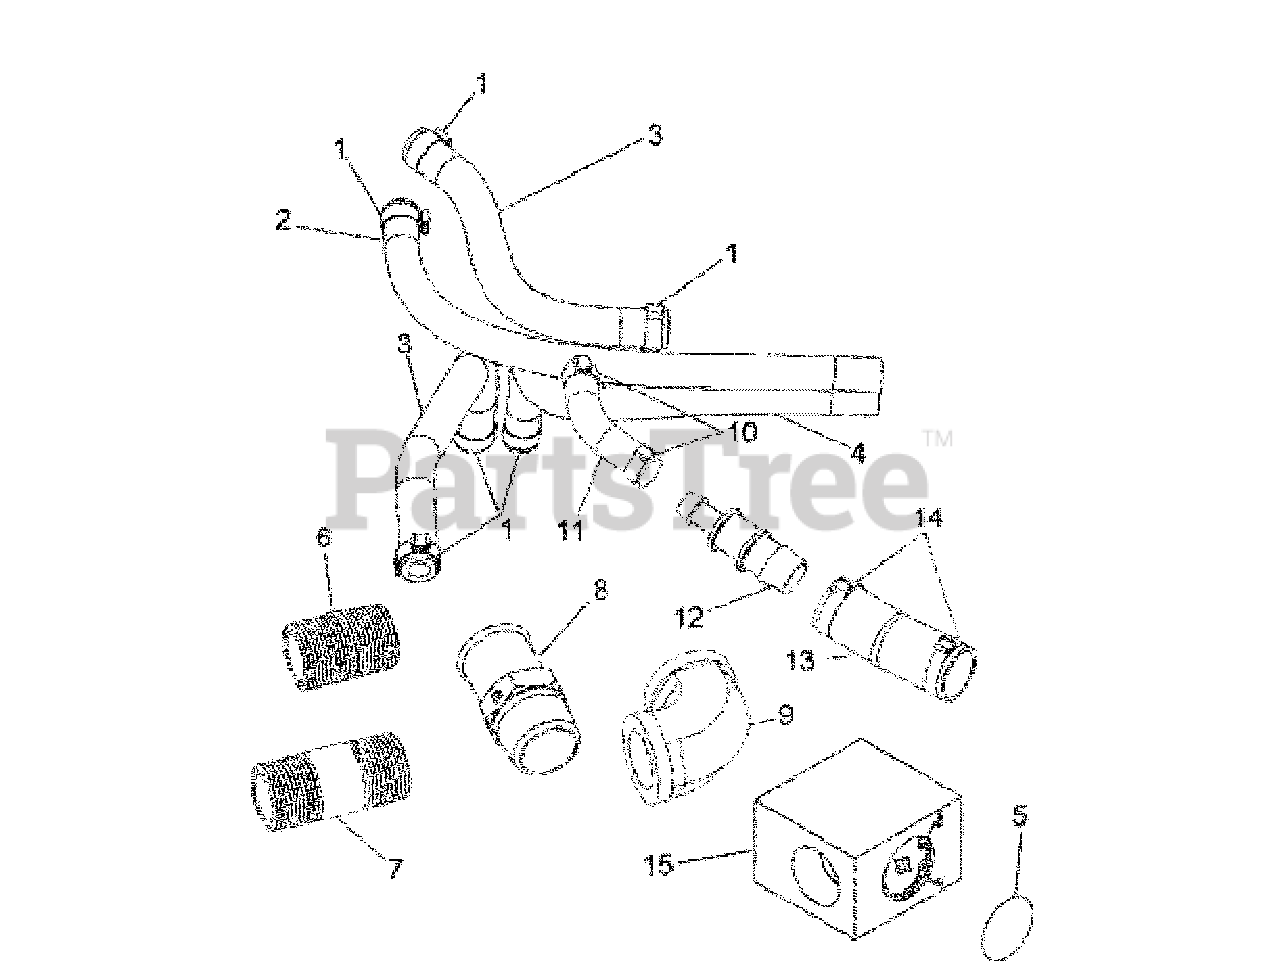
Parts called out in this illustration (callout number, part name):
5	PLUG
6	PIPE
7	PIPE
8	FITTING
9	ELBOW
12	ADAPTER
15	SWITCH
